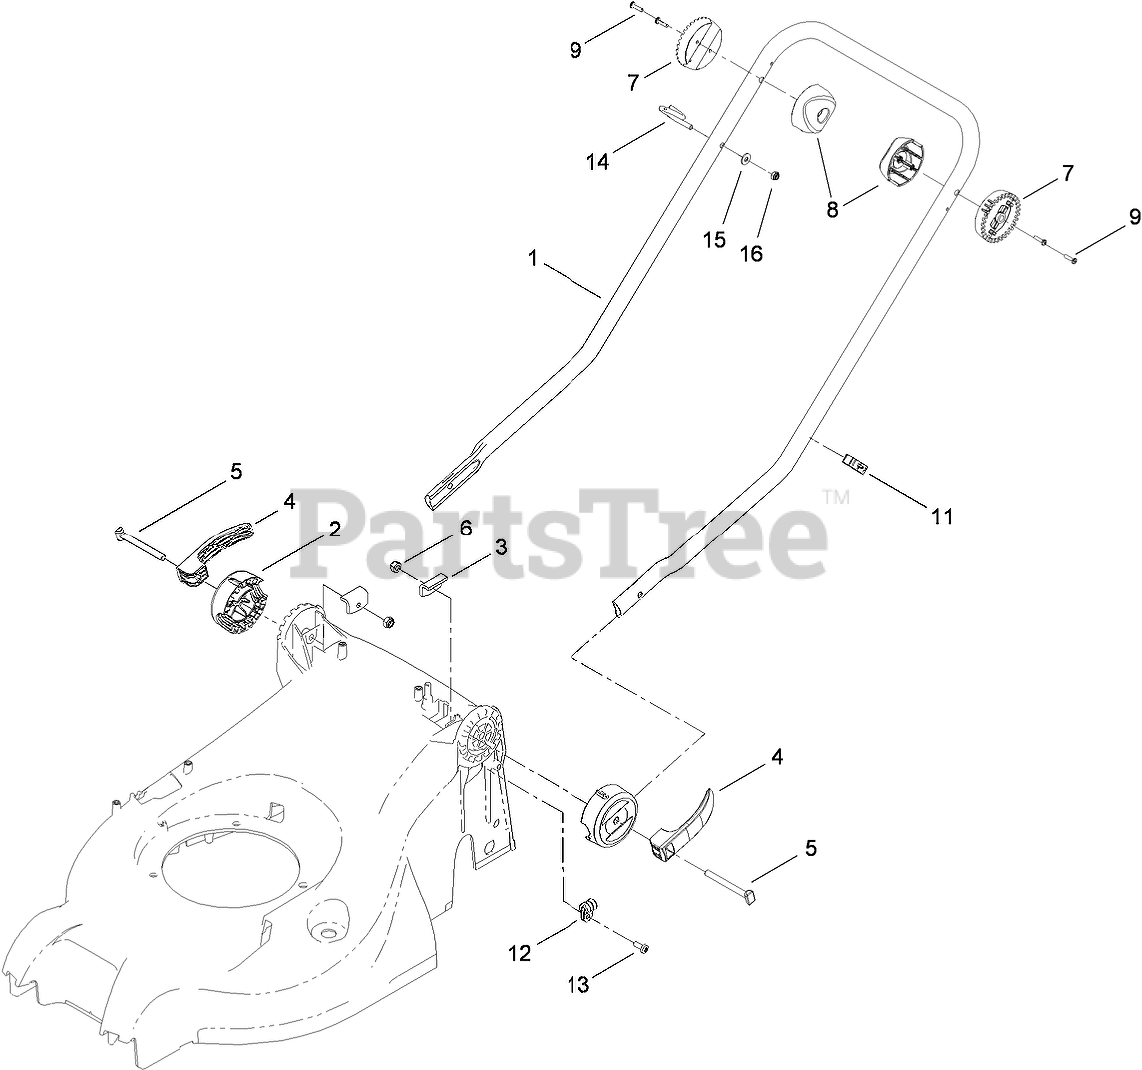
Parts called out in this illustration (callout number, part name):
1	HANDLE-LOWER
2	DISC-HANDLE, LOWER
3	BRACKET-ADJUST, HANDLE
4	LEVER-LOCKING, HANDLE
5	BOLT-T HEAD, LOWER
6	NUT-HEX
7	MOUNT-HANDLE
8	CLAMP-HANDLE
9	SCREW
11	GUIDE-CABLE
12	CLAMP-CABLE
13	SCREW-SPH, THREAD ROLLING
14	GUIDE-ROPE
15	WASHER-FLAT
16	NUT-HEX
